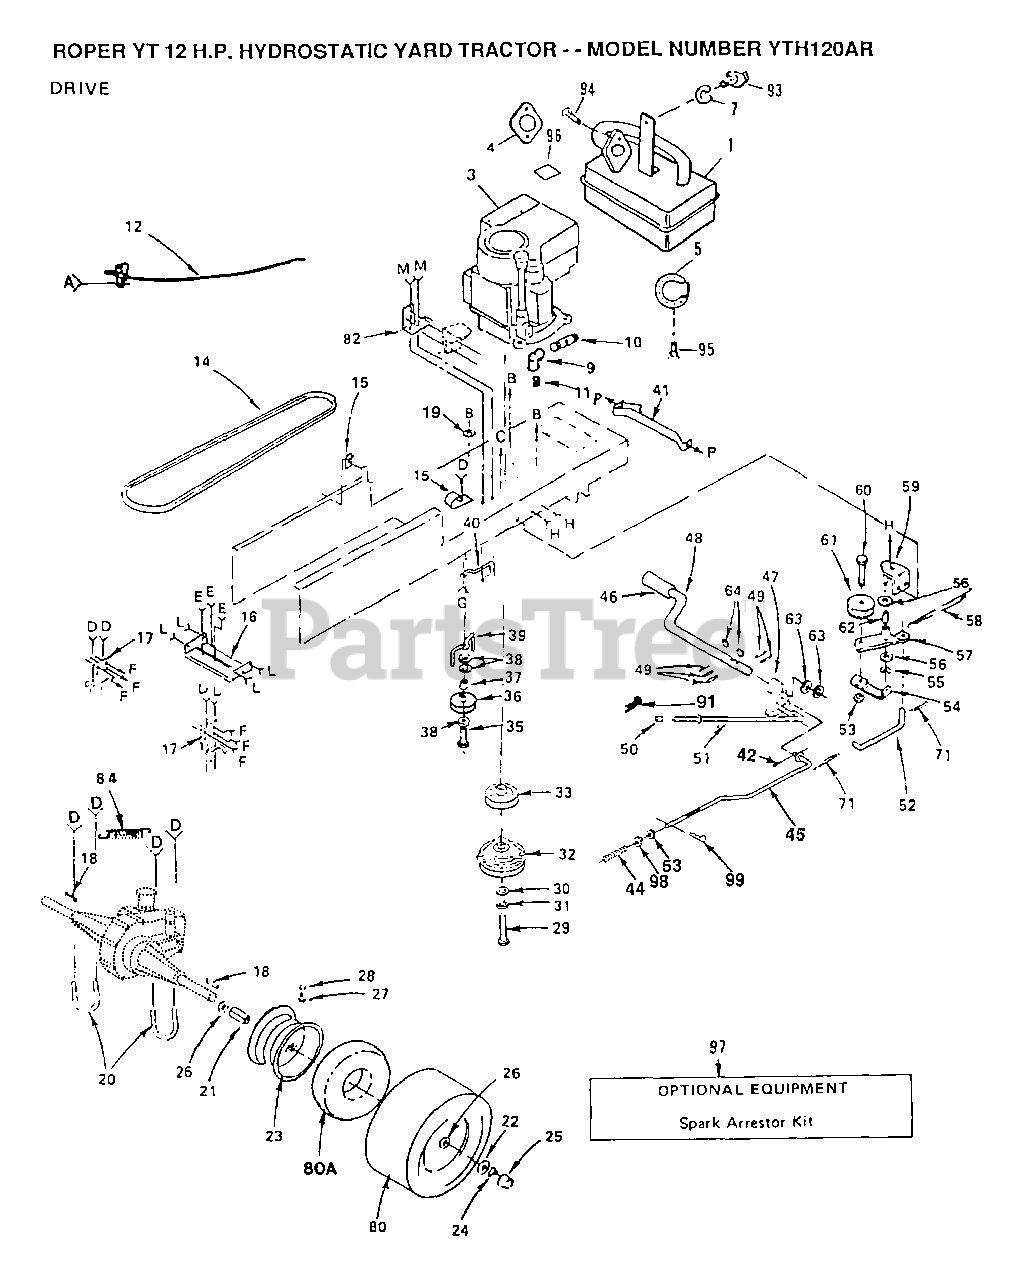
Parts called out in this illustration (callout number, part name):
1	MUFFLER LT
3	ENGINE 12 H.P. TYPE 0201-01
5	DEFLECTOR.222573
7	LOCKWASHER
9	ELBOW
10	NIPPLE PIPE LT
11	PLUG OIL DRAIN
15	CLIP T
16	PLATE TRANS SUPT
19	NUT
20	U BOLT
21	SPACER SPLIT
22	WASHER
24	E-RING LT
25	HUB CAP
27	VALVE STEM LT
28	VALVE CAP
30	WASHER LT
31	LOCKWASHER
35	BOLT
37	SPACER T
38	WASHER
39	"KEEPER,BLT ENG LT"
40	KEEPER BELT ENGLH
42	COTTER PIN
44	SPRING ROD LT
45	ROD BRAKE
46	PEDAL COVER T
47	ARM BRAKE LT
48	SHAFT, FOOT PEDAL
49	LOCKWASHER
50	PLUNGER CAP T
52	"LINK, CLUTCH T"
55	KLIP RING
56	WASHER LT
57	"ASS T, BELLCRAN"
58	"SPRING, RETURN LT"
62	"LY, BEARING"
63	WASHER
71	COTTER PIN
80A	TUBE.18X9.5-8
82	BRACKET LT
91	SPRING.RETAINER
93	BOLT
94	SCREW LT
95	SCREW LT
96	DECAL.ENG.271967
98	NUT
99	RETAINER M
